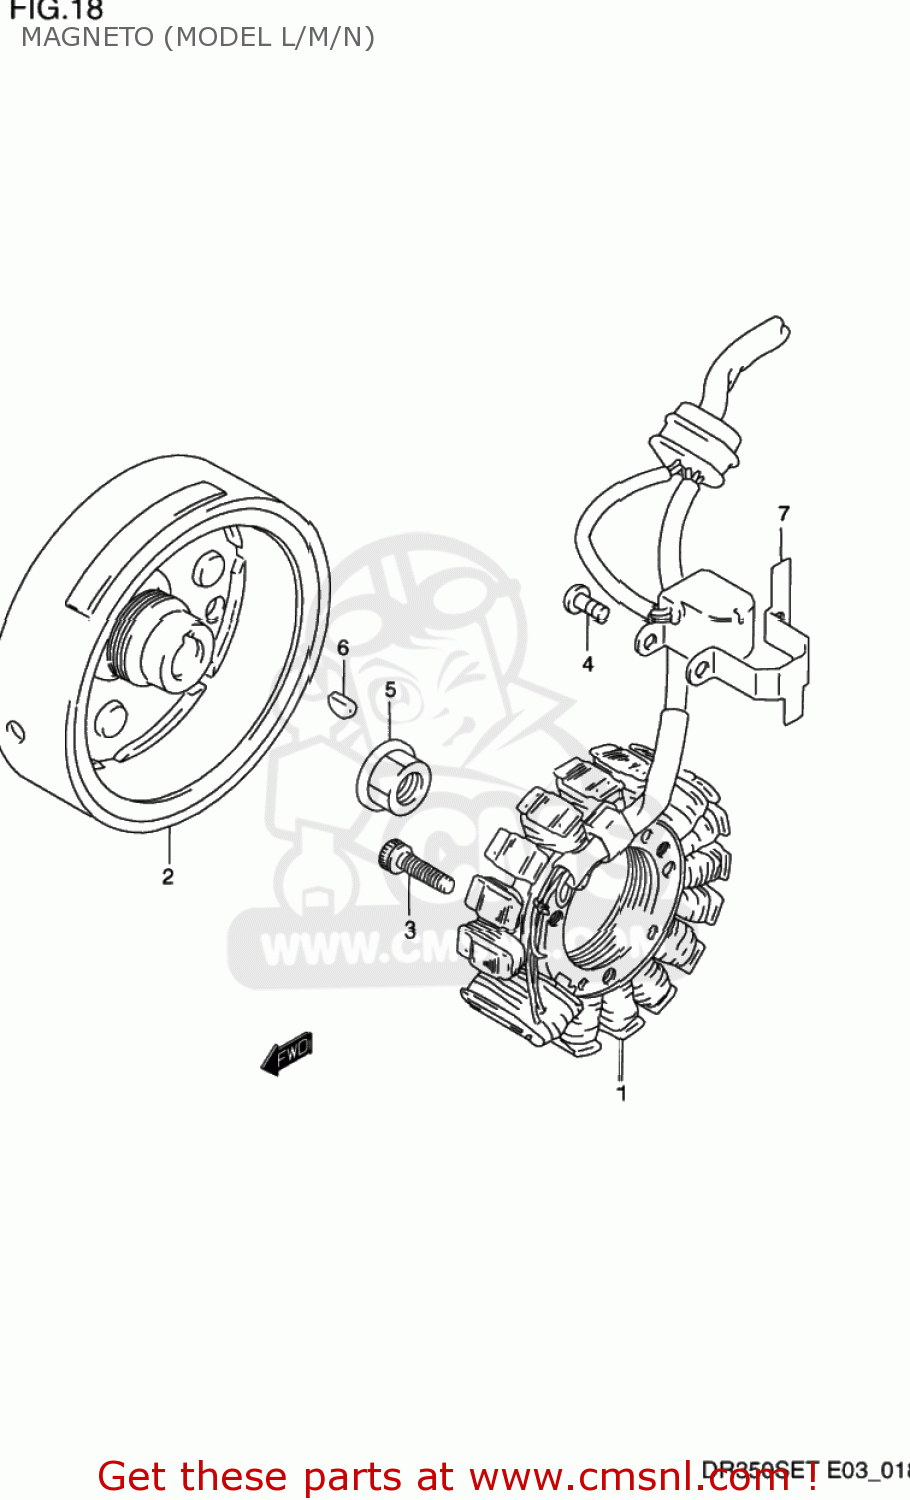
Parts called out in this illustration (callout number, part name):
1	STARTER ASSY
2	ROTOR
3	BOLT
4	SCREW
5	NUT
6	KEY 4MM
7	CLAMP,MAGNETO LEAD WIRE
